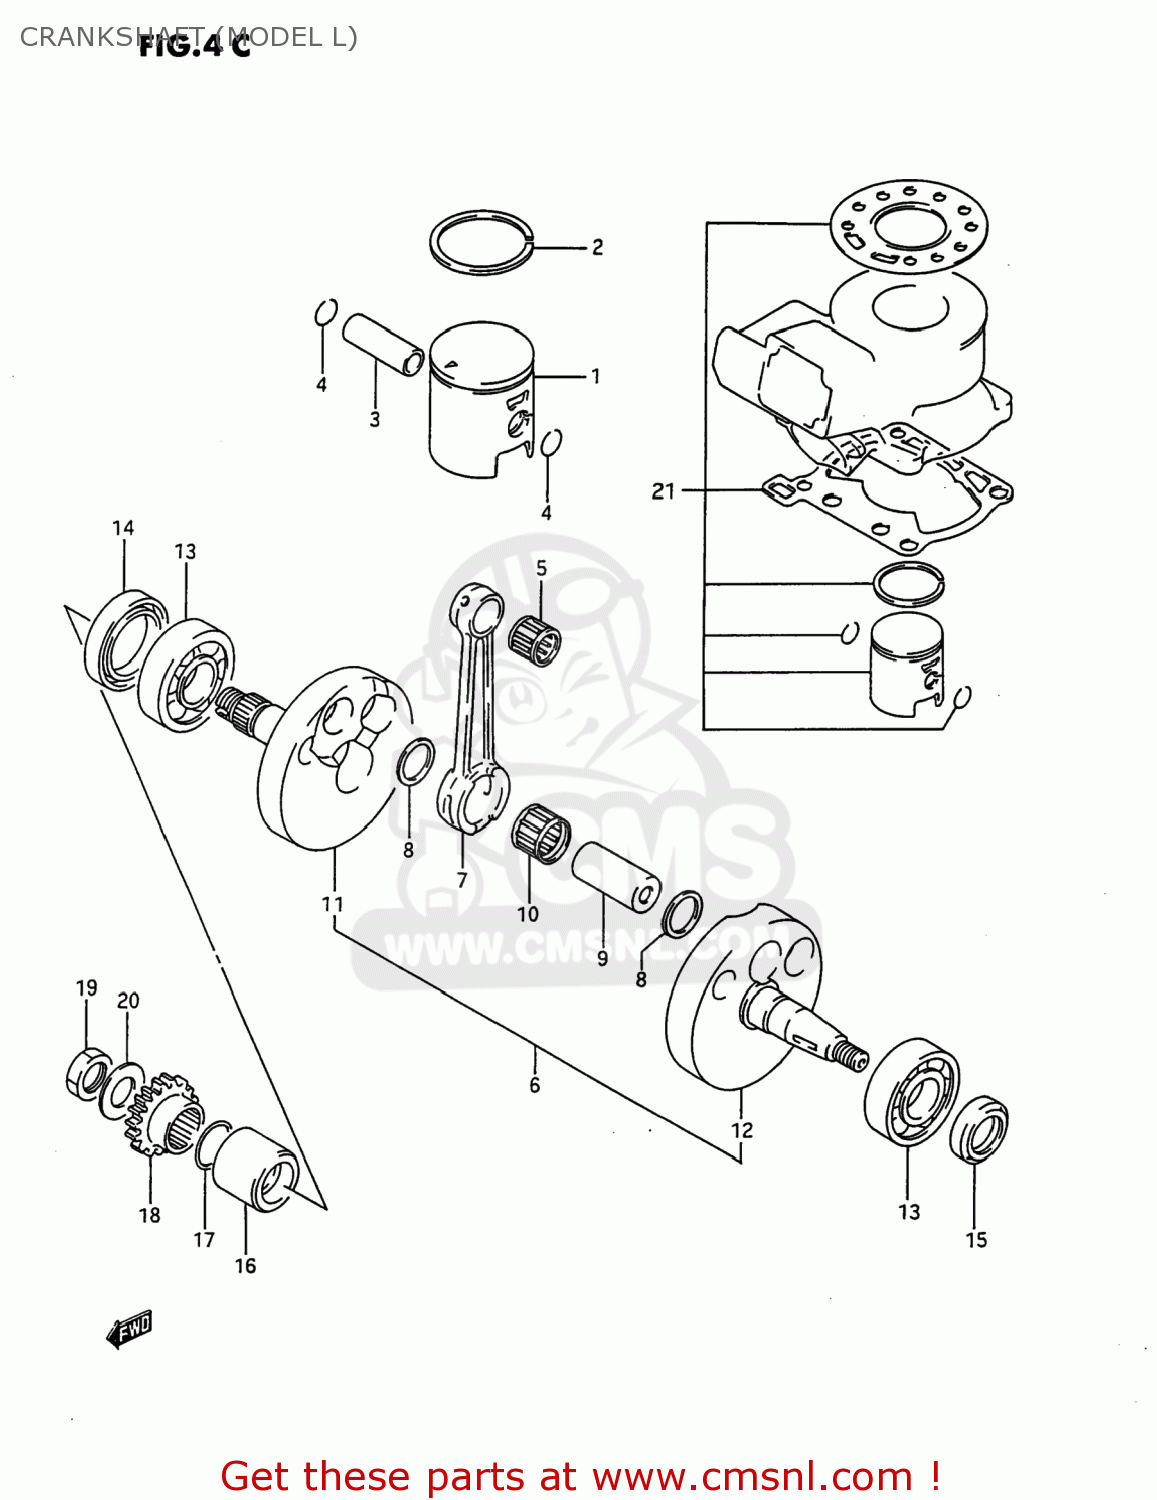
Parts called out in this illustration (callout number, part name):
1	PISTON
2	RING,PISTON
3	PIN,PISTON
4	RING,SNAP 14MM
5	BEARING(14X18X16)
6	CRANKSHAFT ASSEMBLY
7	CONNECTING ROD
8	WASHER
9	PIN,CRANK
10	BEARING,CRANK PIN
11	CRANKSHAFT,RIGHT
12	CRANKSHAFT,LEFT
13	BEARING(20X52X15)
14	OIL SEAL
15	SEAL,OIL(18X30X6)
16	SPACER,PRIMARY DRIVE GEAR
17	O RING(D:2.4,ID:19.8)
18	GEAR,PRIMARY DRIVE (NT:
19	NUT
20	WASHER
21	TOP END KIT,ENGINE (STD)
